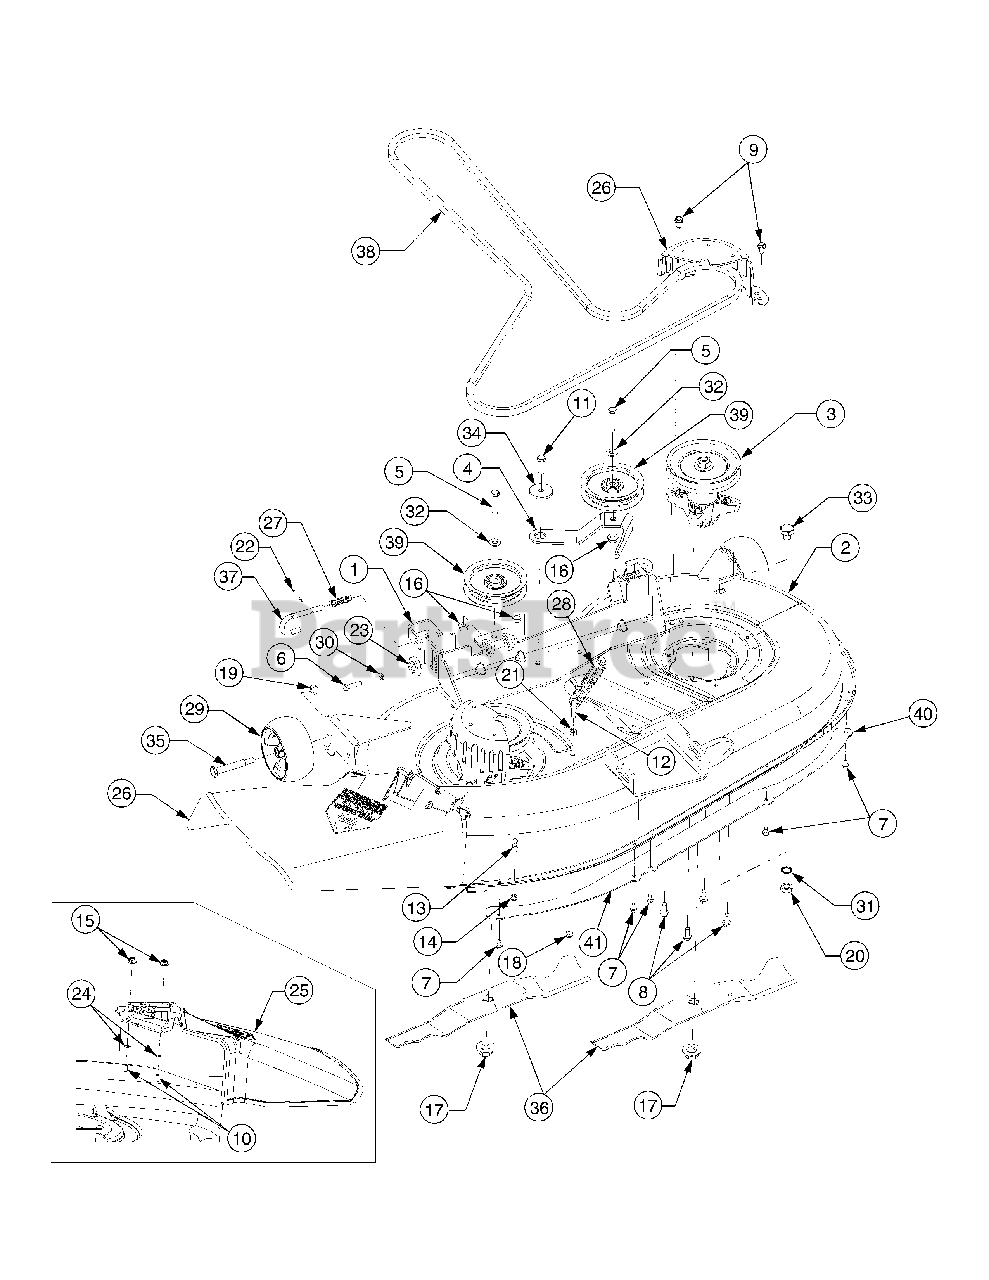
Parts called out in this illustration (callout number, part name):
2	Graphic, Danger
2	Graphic, Instruction
3	Spindle Assembly
3	Pulley
5	Screw, Hex Cap, 3/8-16 x 1.75 GR5
6	Screw, Hex Cap, 5/16-18 x 1.25 GR5
7	Screw, Hex Wash. Hd. Tapp 1/4-20 x .5
8	Screw, Hex Wash. Hd. Tapp 5/16-18 x .875
9	Screw, Hex Wash. Hd. Tapp 5/16-12 x .75
10	Screw, Hex Cap, 1/4-20 x .62 GR5 ..
11	Screw, Hex Cap, 3/8-16 x 1.25 GR5
12	Screw, Hex Cap, 5/16-18 x 1.75 GR5
13	Pin, Grass Catcher, 1/4-20
14	Nut, Hex Insert Lock, 1/4-20 GR8
15	Nut, Hx Insert Flange Lck, 1/4-20 GR5
16	Nut, Hx Insert Flange Lck, 3/8-16 GrF
17	Nut, Hex Flange, 5/8-18
18	Nut, Hex Insert Lock, 5/16-18 GR5 ..
19	Nut, Hex Flange Lock, 3/8-16 GrF
20	Nut, Hex, M16-1.5
21	Nut, Hex, 5/16-18 GR5
22	Pin, Cotter, 1/8 x 1.25
23	Gear, Deck Adjustment
24	Nut, Push, .25 x .5
25	Chute Assembly, Discharge
25	Graphic, Danger
26	Cover, Belt
27	Spring, Compression
28	Spring, Extension, .94 Dia. x 6.74
29	Wheel, Deck Ball, 5.0
30	Washer, Lock, 5/16
31	Washer, Lock,
32	Washer, Flat, .38 x .93 x .11 HT
33	Plug, Screw, M16 x 1.5
34	Spacer, Shoulder, .884 x .19
35	Screw, Shoulder, .5 x 2.5:3/8-16
36	Blade, 3 in 1, 21.23
37	Rod, Deck Hanger
38	Belt, V, Type A Sec x 109
39	Pulley, Idler, 4.25 Dia.
